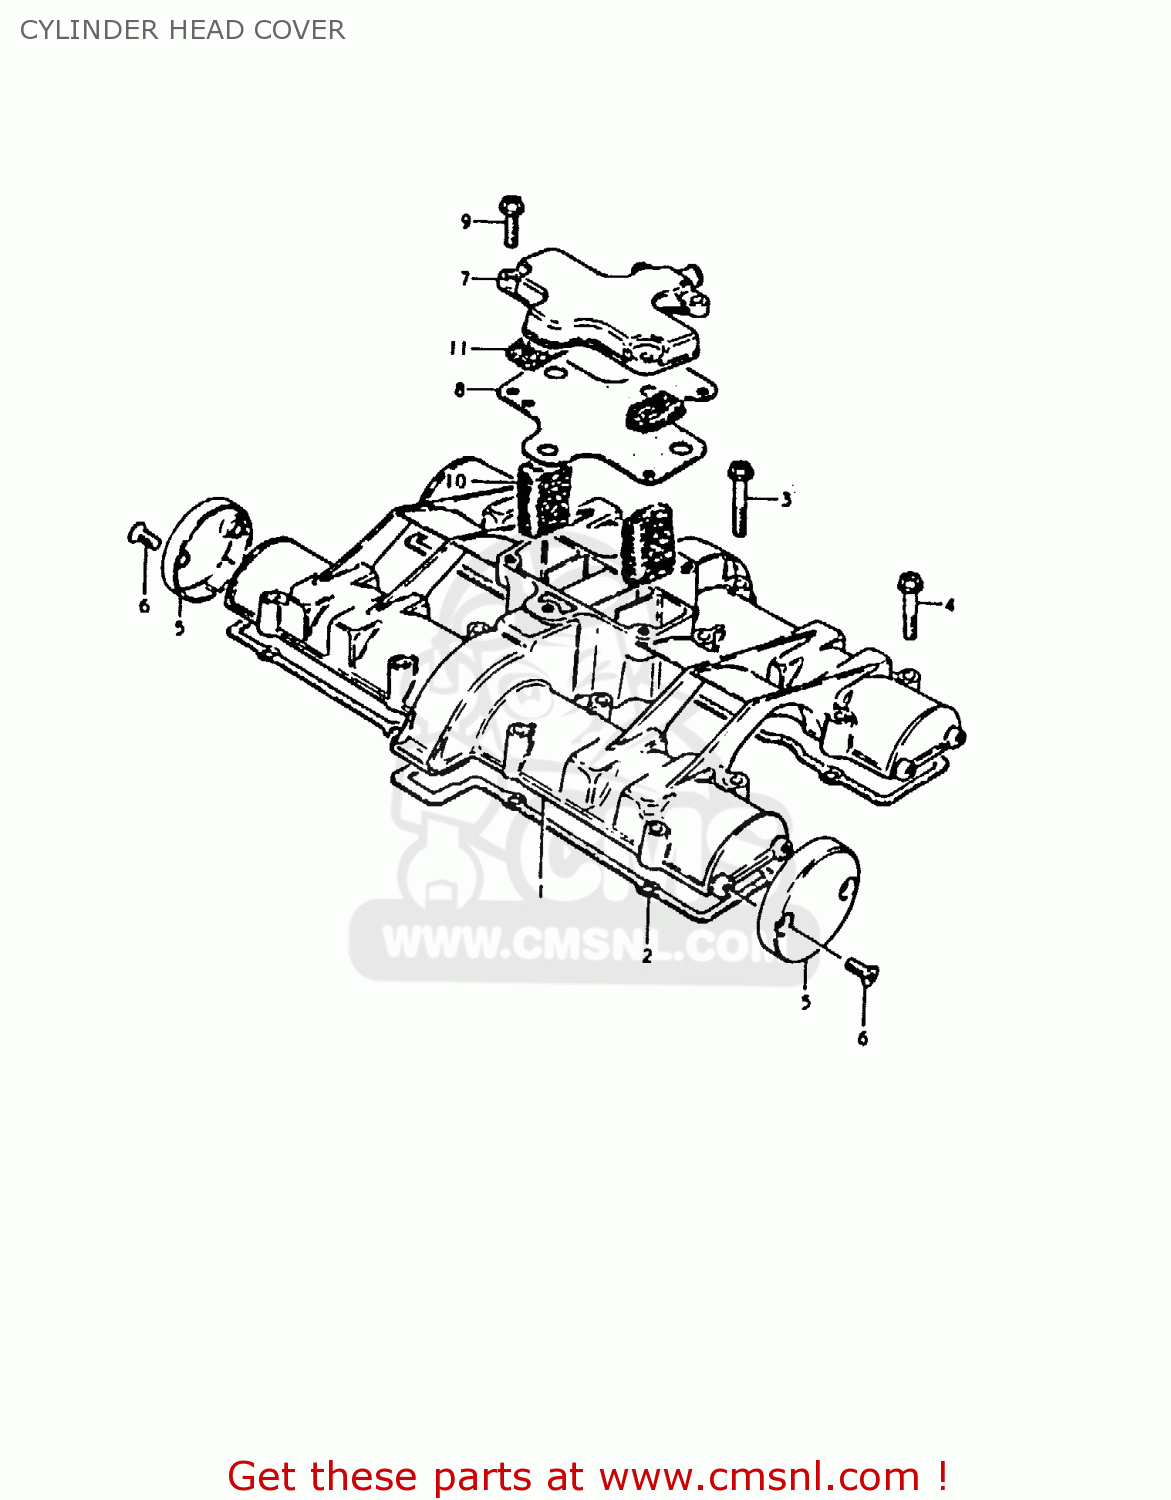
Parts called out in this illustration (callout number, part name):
1	COVER,CYLINDER HEAD
2	GASKET,CYLINDER HEAD COVER (MCA)
3	BOLT
4	BOLT 6X35
5	CAP,CYLINDER HEAD COVER
6	SCREW 5X12
7	COVER,BREATHER
8	GASKET (MCA)
9	BOLT
10	COVER,BREATHER
11	SEPARATOR,OIL BREATHER
